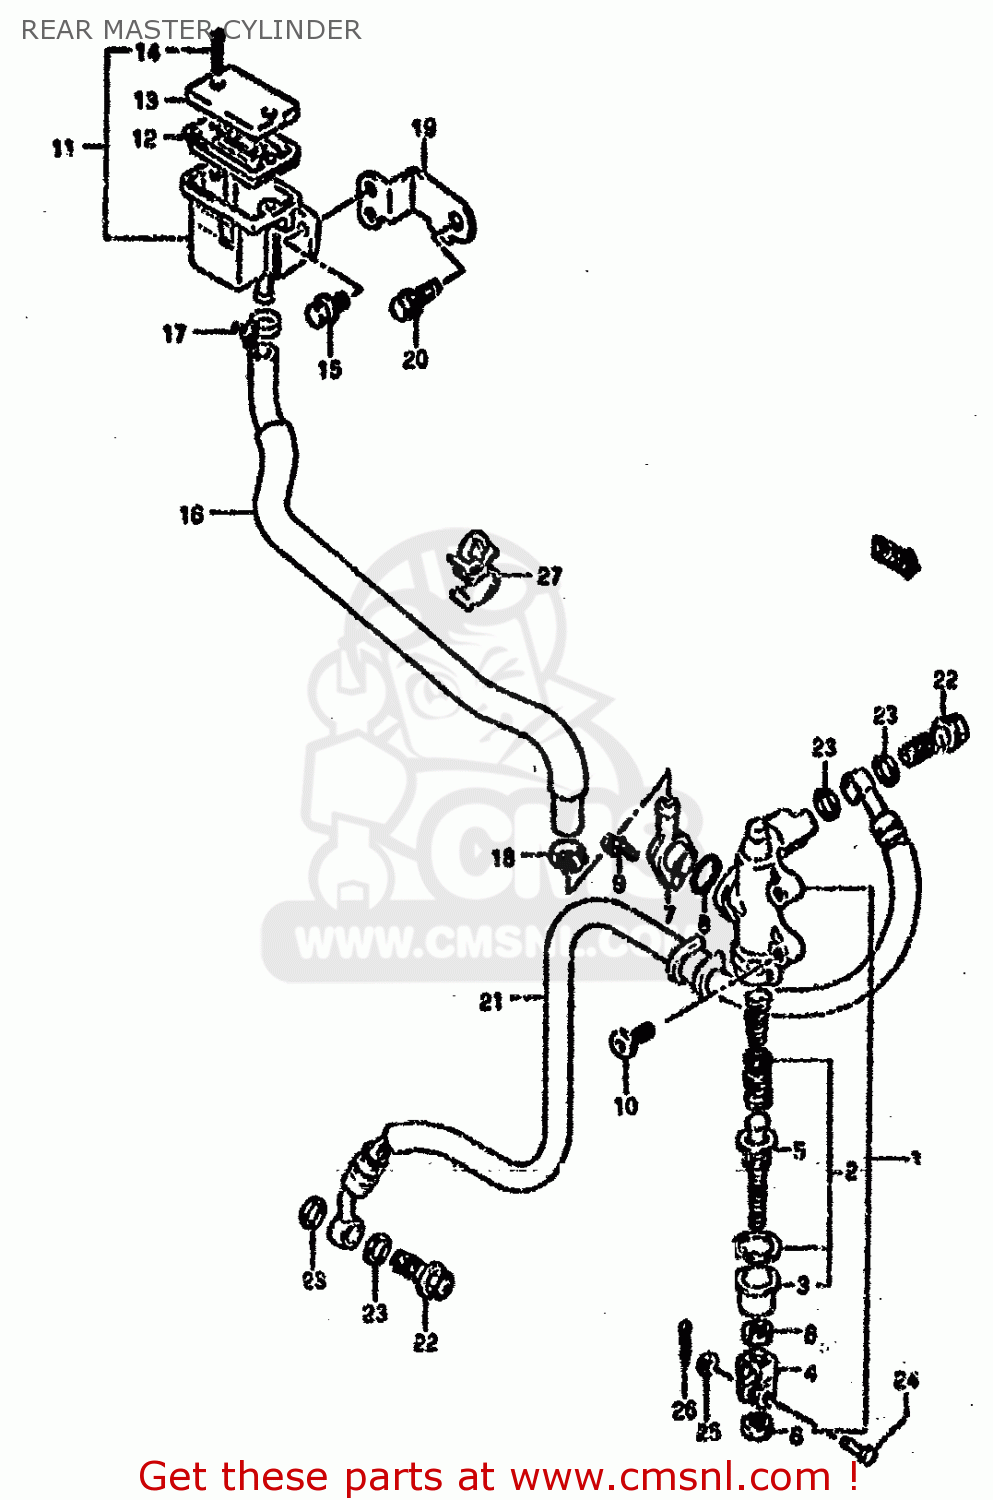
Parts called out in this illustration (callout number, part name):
1	CYLINDER ASSEMBLY,REAR MASTER
2	PISTON/CUP SET
3	BOOT
4	YOKE
5	ROD,PUSH
6	NUT
7	CONNECTOR
8	O RING
9	SCREW
10	SCREW(8X22)
11	TANK ASSY,RESERVOIR
12	DIAPHRAGM
13	CAP
14	SCREW
15	BOLT
16	HOSE,RESERVOIR TANK
17	CLAMP
18	CLAMP
19	PLATE,RESERVOIR TANK
20	BOLT
21	HOSE,RR BRAKE
22	BOLT UNION
23	WASHER(10X15X1.5)
24	PIN
25	WASHER
26	PIN
27	CLAMP
